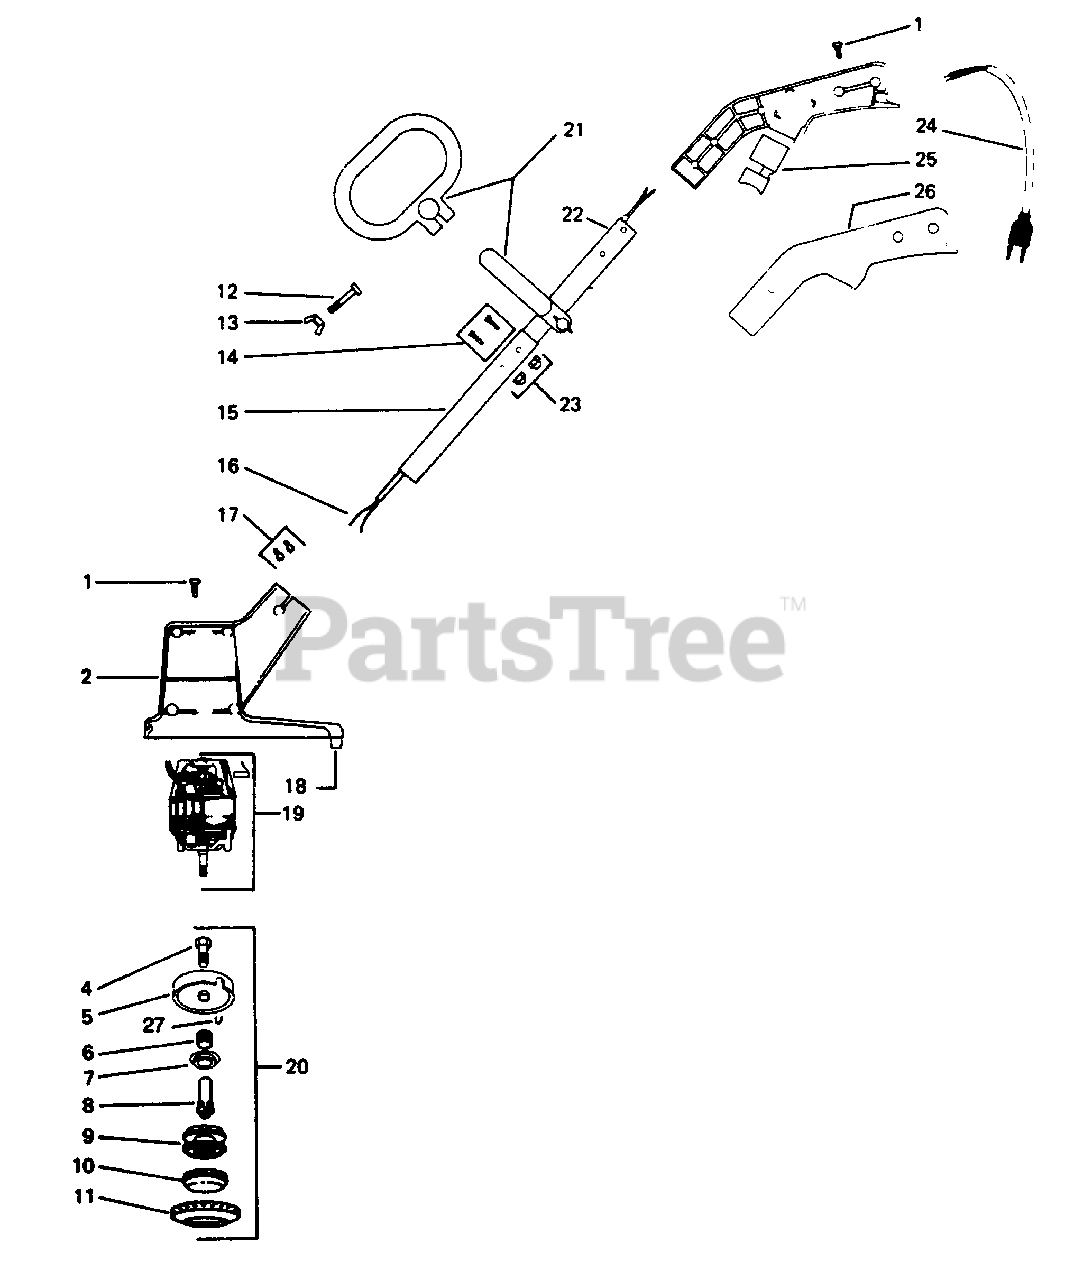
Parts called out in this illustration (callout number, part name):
2	MOTOR HOUSING SET ONLY
4	DRIVE ADAPTOR
5	HUB W/LINE SAVER
6	COIL SPRING
7	COIL SPRING ADAPTOR
8	DRIVE GEAR
9	SPOOL W/LINE
10	RELEASE BUTTON
13	WING NUT
15	LOWER HANDLE TUBE
16	WIRING HARNESS
17	CONNECTOR
18	TAIL INTERFERENCE BLADE
20	TAP-N-GO HEAD ASSEMBLY (COMPLETE)
21	ASSIST HANDLE
22	UPPER HANDLE TUBE
23	NUT, ACORN
24	POWER CORD PIGTAIL
26	TRIGGER HANDLE (SET ONLY)
27	LINE SAVER
